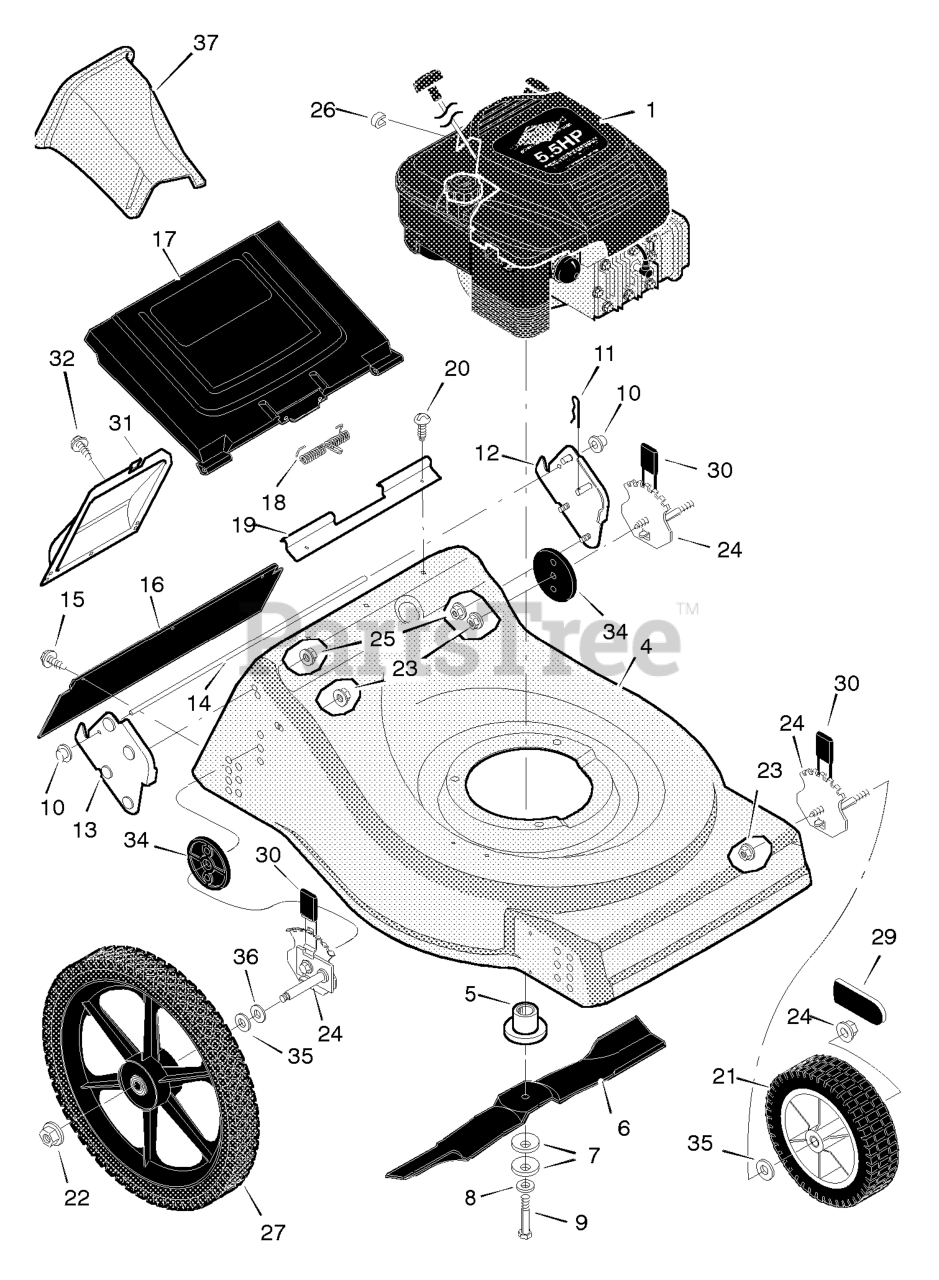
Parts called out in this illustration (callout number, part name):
1	Engine *
3	Bolt, Engine
4	Housing
5	Adapter, Blade
7	Washer, Belleville
9	Bolt, Hex
10	Push- On Cap
11	Pin, Hair
12	Bracket, Left Handle
13	Bracket, Right Handle
14	Rod, Door Pivot
16	Deflector, Rear
17	Door, Rear
18	Spring, Torsion
19	Spacer, Door
21	Wheel and Tire *
22	Nut, Flange
23	Nut, Flange
24	Height Adjuster
25	Nut, Flange
26	Stop, Rope
27	Wheel and Tire, Rear
28	Hub Cap
29	Hub Cap
31	Cover, Rear
37	Plug, Mulcher
